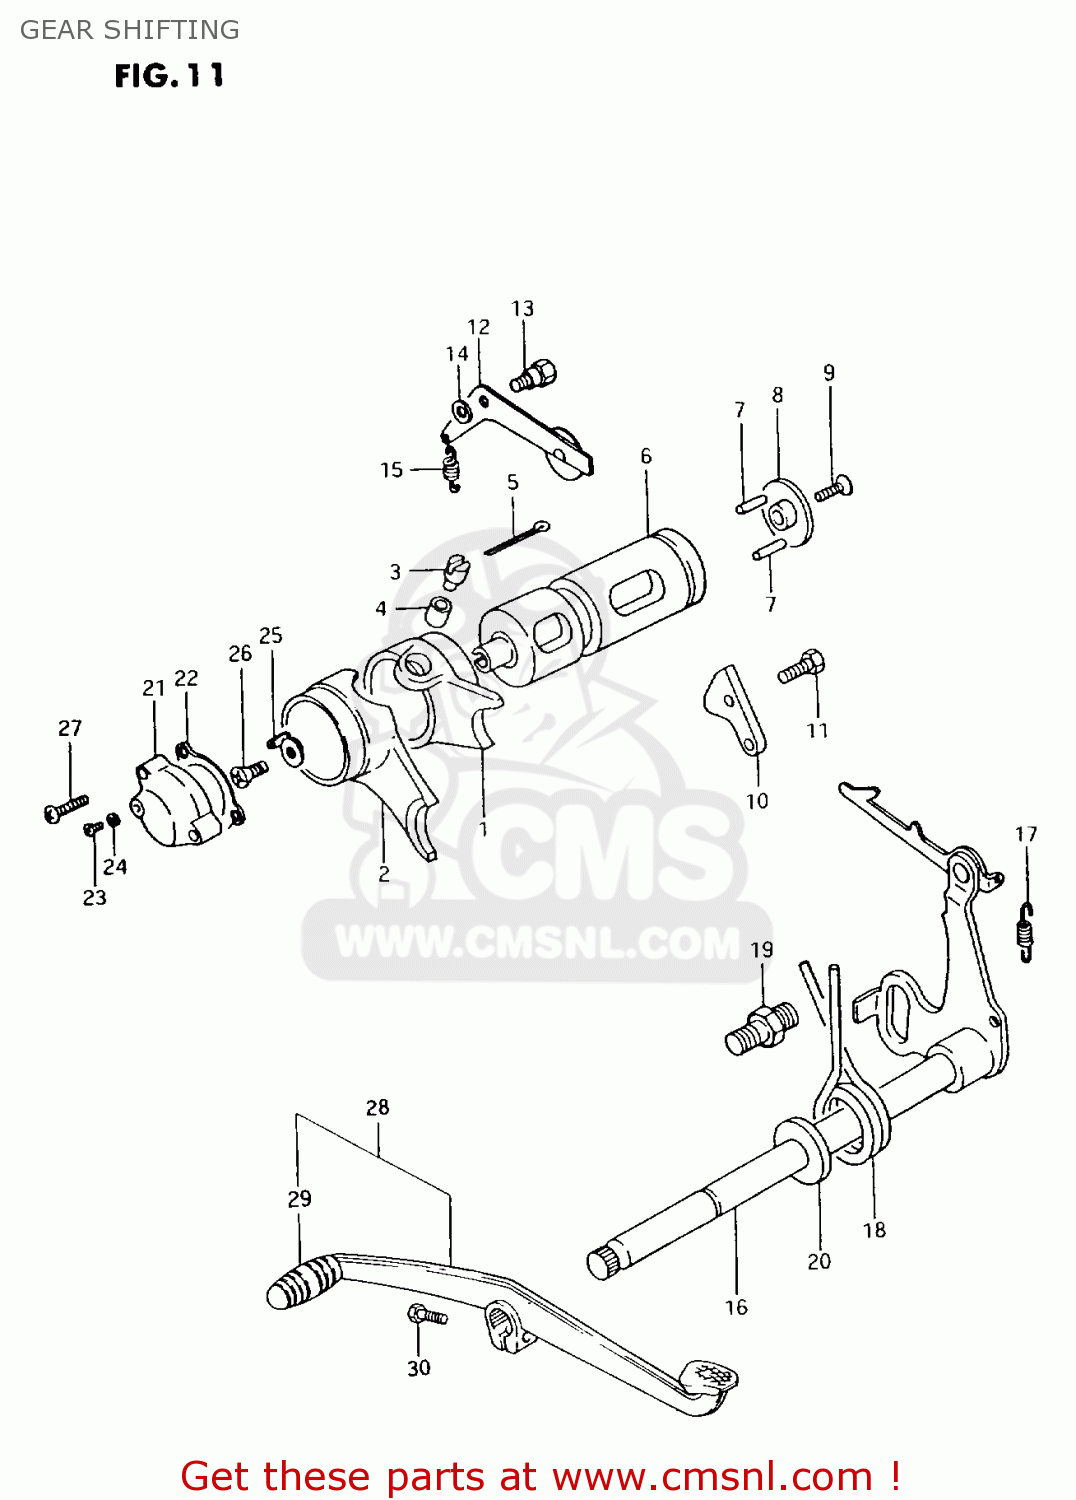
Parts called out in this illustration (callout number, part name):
1	FORK, GEAR SHIFTING NO. 1
2	FORK,GEAR SHIFT
3	PIN
4	SPACER(6X9.8X6)
5	PIN 25X20
6	CAM,GEAR SHIFT
7	PIN(4X20)
8	HOLDER,GEAR SHIFTING C
9	SCREW
10	GUIDE,GEAR SHIFT CAM
11	BOLT
12	STOPPER,GEAR SHIFT CAM
13	BOLT(6X16.1)
14	WASHER
15	SPRING
16	SHAFT,GEAR SHIFT
17	SPRING
18	SPRING
19	STOPPER,GEAR SHIFT ARM
20	OIL SEAL
21	SWITCH,NEUTRAL INDICATOR
22	GASKET,GEAR SHIFT SWITCH (NAS)
23	SCREW
24	WASHER
25	CONTACT,GEAR SHIFT SWITCH
26	SCREW
27	SCREW
28	LEVER ASSY,GEAR SHIFT
29	RUBBER,GEAR SHIFT PEDAL
30	BOLT
